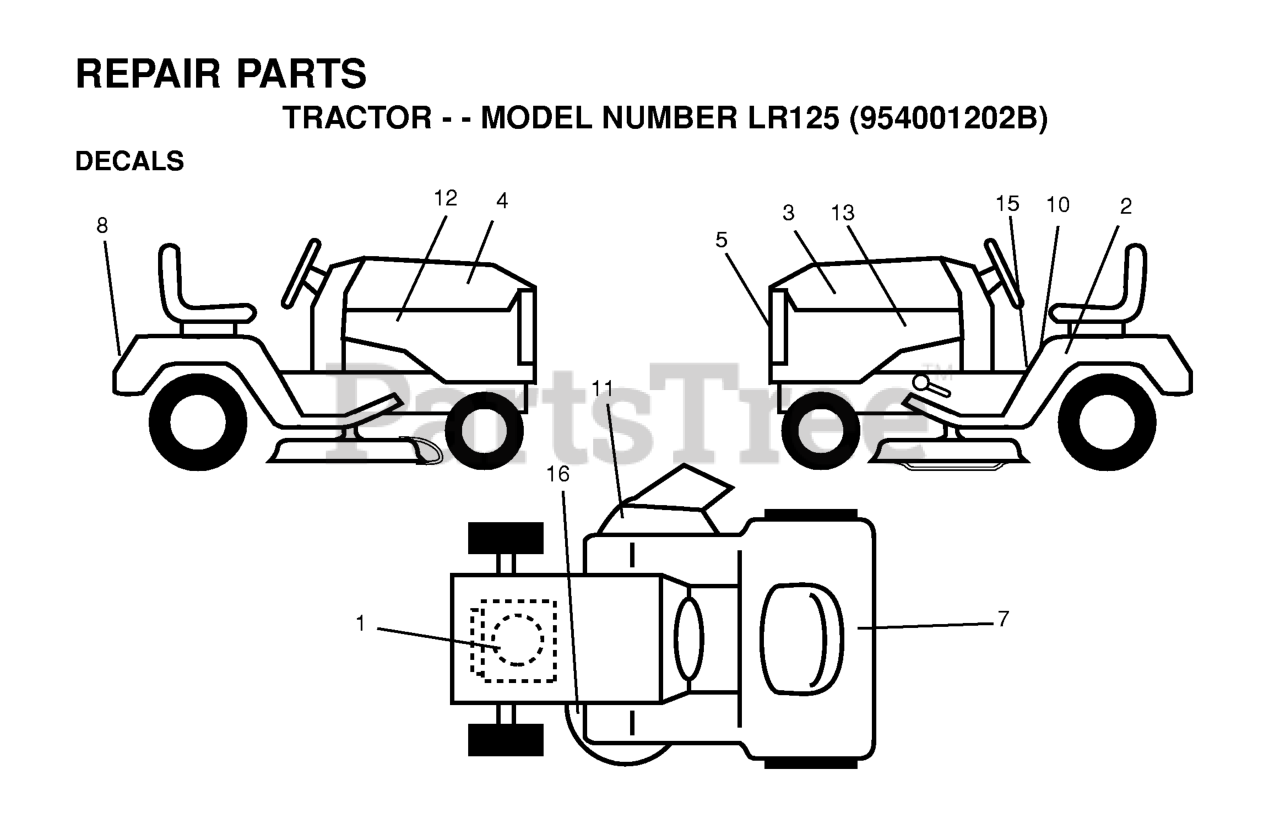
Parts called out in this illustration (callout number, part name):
3	HOOD DECAL LH
4	HOOD DECAL RH
5	DECAL-GRILL
7	DECAL BTRY SYMBOLS
8	DECAL FENDER NLA
10	DECAL CAUTION
11	DECAL WARNING (ENGLISH/FRENCH)
12	DECAL HOOD RH
13	DECAL HOOD LH
15	DECAL OPER INSTRUCTION
16	DECAL V-BELT SCHEMATIC
